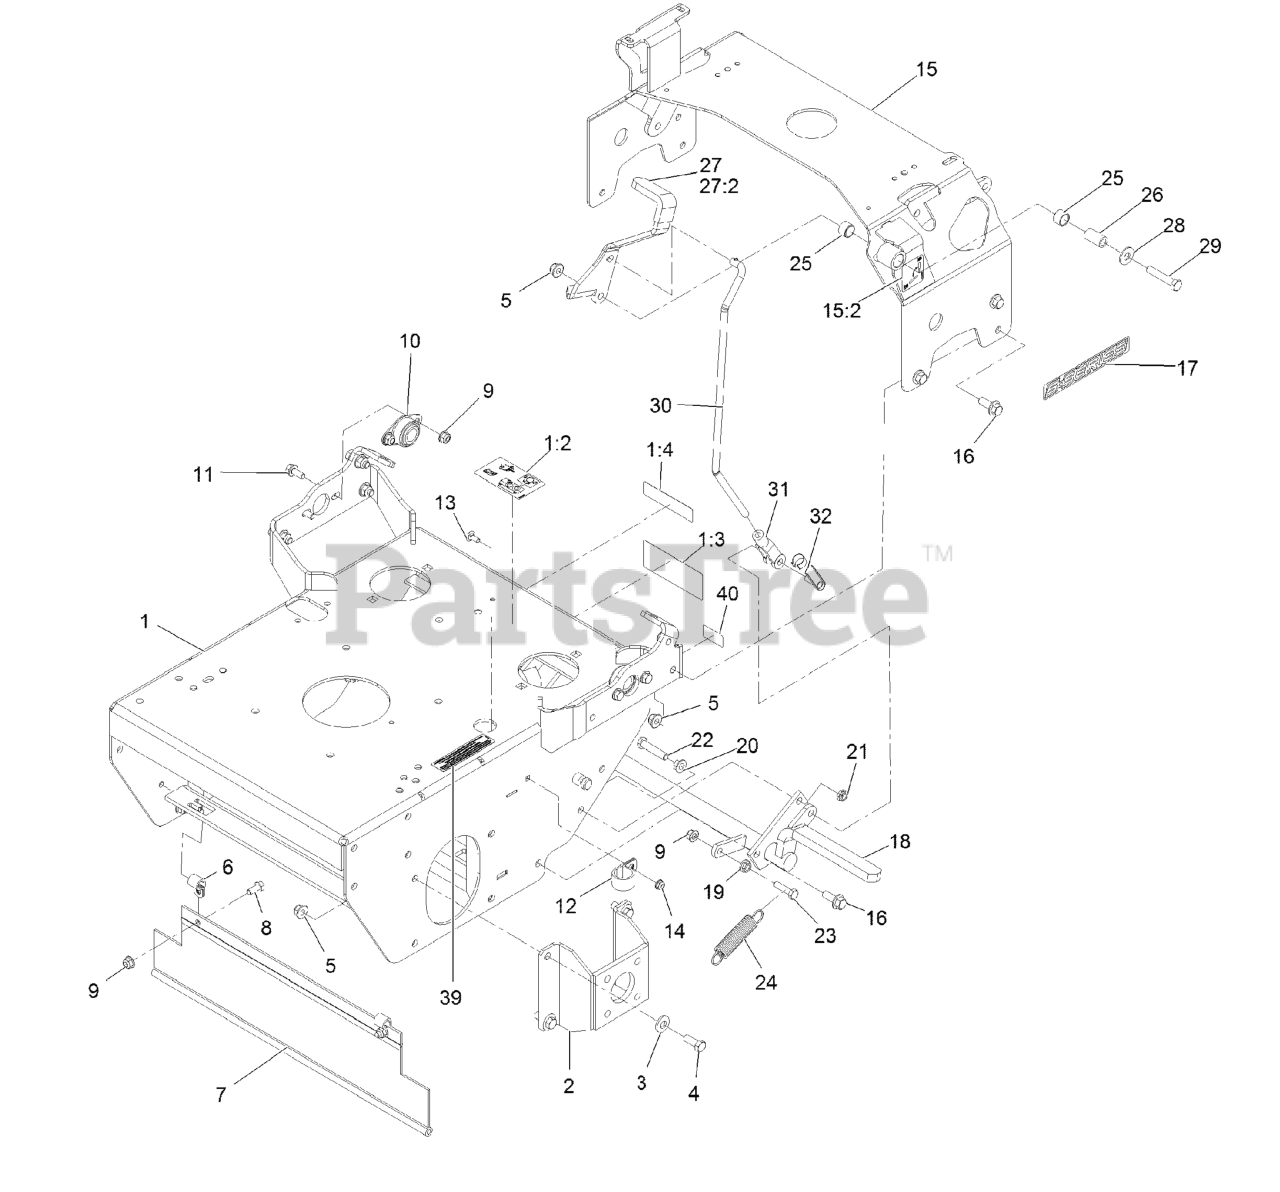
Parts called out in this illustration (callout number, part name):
1	ASM, ENGINE DECK W/ DECAL
1:2	DECAL-DRIVE RELEASE
1:3	DECAL-WARNING, SULKY
1:4	DECAL-WARNING
2	WLD,MOTOR MOUNT 48&52
3	WASHER-BELLEVILLE
4	SCREW-HH
5	NUT-HF, NI
6	CLIP-LOOM
7	SHIELD-DRAG
8	SCREW-HH
9	NUT-HF, NI
10	BEARING-FLANGE, SIDE
11	SCREW-HHF
12	CLIP-LOOM
13	SCREW-CARR
15	ASM, TANK SUPPORT W/ DECA
15:2	DECAL-PARK BRAKE, CE
16	SCREW-HHF 3/8-16 X 1
17	DECAL-S-SERIES
20	NUT-HHF, WHIZ
21	NUT-LOCK, NI
22	SCREW-HH
23	SCREW-HH
24	SPRING-IDLER
25	SLEEVE-BUSHING
26	BUSHING-PIVOT
27	ASM, BRAKE LEVER W/ GRIP
27:2	GRIP-LEVER
28	WASHER-FLAT
29	SCREW-HH
30	LINKAGE, BRAKE
31	YOKE-LINKAGE, BRAKE
32	PIN-SPRING, CLEVIS
39	DECAL-ARRESTER, SPARK
40	Decal-Patent
